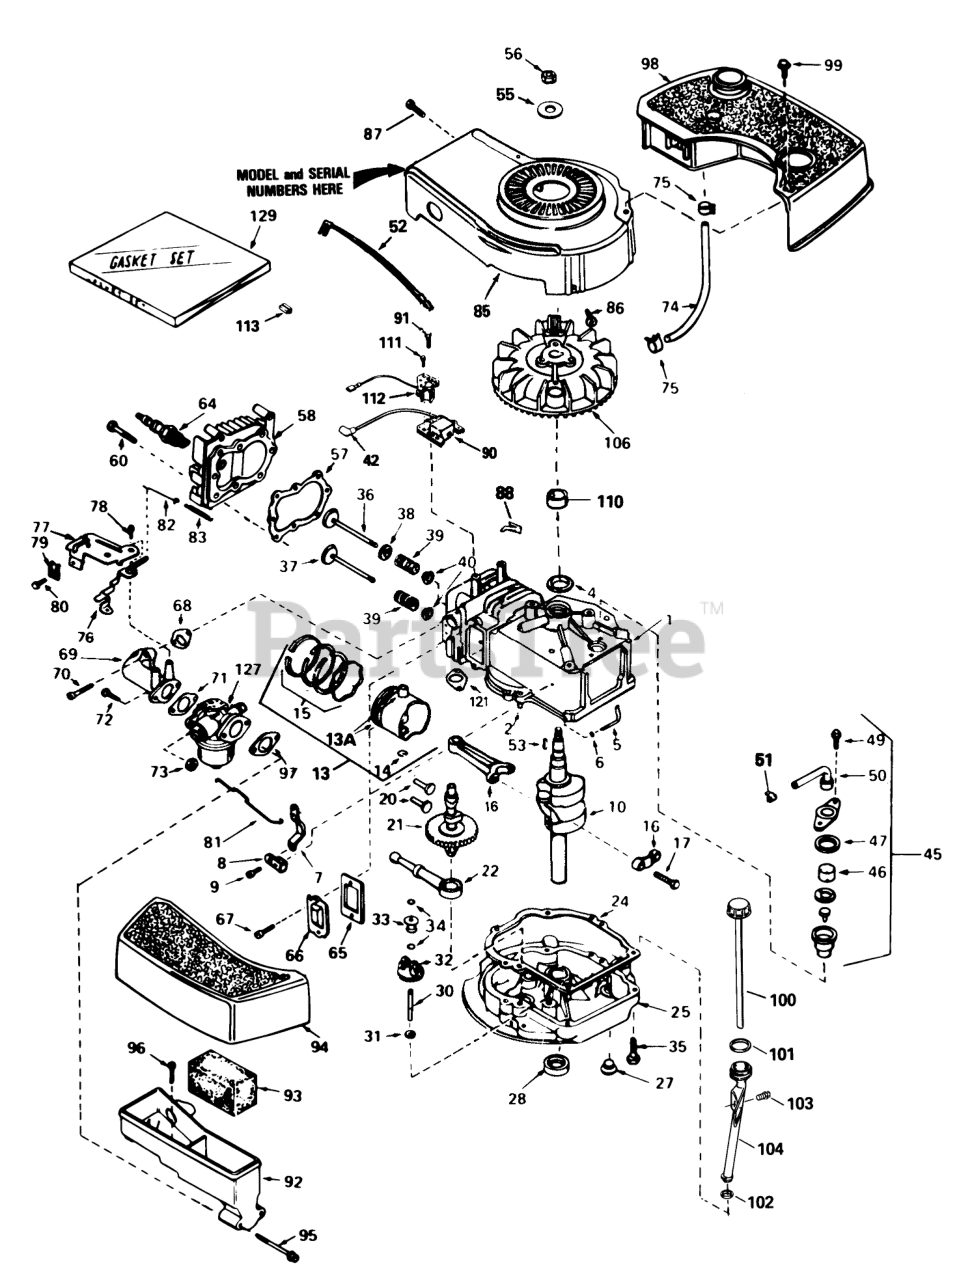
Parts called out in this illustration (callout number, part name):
1	Cylinder Assembly (Incl. Ref. #2 & 4)
2	Pin-Dowel
4	Seal-Oil
5	Rod, Governor (Incl. Ref. #6)
6	Washer-Flat
7	Governor Lever
8	Clamp-Lever, Governor
9	Screw
10	Crankshaft
13	Piston, Pin & Ring Assy. (Std.)(Incl. Ref. #13A, 14 & 15)
13	Piston, Pin & Ring Assembly (.010 oversize)(Incl. Ref. #13A, 14 & 15)
13	Piston, Pin & Ring Assembly (.020 oversize)(Incl. Ref. #13A, 14 & 15)
13A	Piston & Pin Assembly (Std.)(Incl. Ref. #14)
13A	Piston & Pin Assembly (.010 oversize)(Incl. Ref. #14)
13A	Piston & Pin Assembly (.020 oversize)(Incl. Ref. #14)
14	Ring-Retaining, Piston Pin
15	Ring Set-Piston (Std.)
15	Ring Set, Piston(.0100versize)
15	Ring Set (.020" OS)
16	Rod Assembly, Connecting (Incl. Ref. #17)
17	Bolt-Rod, Connecting
20	Lifter-Valve
21	Camshaft(Mech.Comp. Release)
22	Oil Pump ASM
24	Gasket
25	Flange Assembly, Mounting (Incl. Ref. #27, 28 & 30)
27	Plug Oil Drain
28	Seal Oil
30	Shaft-Governor
31	Washer-Flat
32	Gear Assembly, Governor (Incl. Ref. #31)
33	Spool-Governor
34	Ring-Retaining
35	Screw (1/4-20 x 1-1/4)
36	Valve, Intake (Std.)(Incl. Ref. #40)
36	Valve, Intake (1/32" oversize)(Incl. Ref. #40)
37	Valve, Exhaust (Std.)(Incl. Ref. #40)
37	Valve, Exhaust (1/32" oversize)(Incl. Ref. #40)
38	Seal Assy., Intake
39	Spring-Valve
40	Cap-Valve, Spring
42	Cover-Spark Plug
45	Breather Assembly (Incl. Ref. #46 thru 51)
46	Element-Breather
47	Gasket-Breather
49	Screw (10-24 x 9/16)
50	Tube, Breaker
51	Clip, Breather
52	Wire-Ground
53	Key-Flywheel
55	Washer-Belleville
56	Nut-Flywheel
57	63573 GIL 42 SNWTHW
58	Head-Cylinder
60	Screw (5/16-18x1-1/2)
64	Spark Plug-Resistor (R J19 L M)
65	Gasket-Breather
66	Cover-Valve
68	Gasket-Intake
69	Pipe, Intake (Incl. Ref. #68)
70	Screw (1/4-20 x 1)
71	Gasket-Carburetor
72	Screw (1/4-28 x 7/8)
73	Nut and Lock Washer (1/4-28)
74	Line-Fuel
75	Clamp-Line, Fuel
76	Lever Control
77	Control Assembly, Speed (Incl. Ref. #76 & 78)
78	Screw, Hex Washer Hd Shoulder Self-Tap
79	Conduit
80	Screw (10-32 x 3/8)
81	Link-Throttle
82	Link Governor Spring
83	Spring Governor
85	Housing-Blower
86	Screw (1/4-20x19/32)
87	Screw (10-24 x 9/16)
88	Clip-Wire
90	Solid State
91	Screw
92	Body Air Cleaner
93	Filer, Air
94	Cove, Air Cleaner
95	Screw Fil Hd.
96	Screw, Hex Washer Hd Shoulder Self-Tap
97	Gasket-Air Cleaner
98	Tank, Fuel (Inc. Ref. #75)
99	Screw (10-32 x 35/64)
100	Dipstick, Oil
103	Screw (10-32 x 1/2)
104	Tube, Oil Fill
106	Flywheel
111	Screw (8-32x27/64)
112	Coil, Alternator
113	Connector-Body
121	Gasket Exhaust
127	Carburetor (Incl. Ref. #71)
129	Gasket Set (Incl. items marked)
